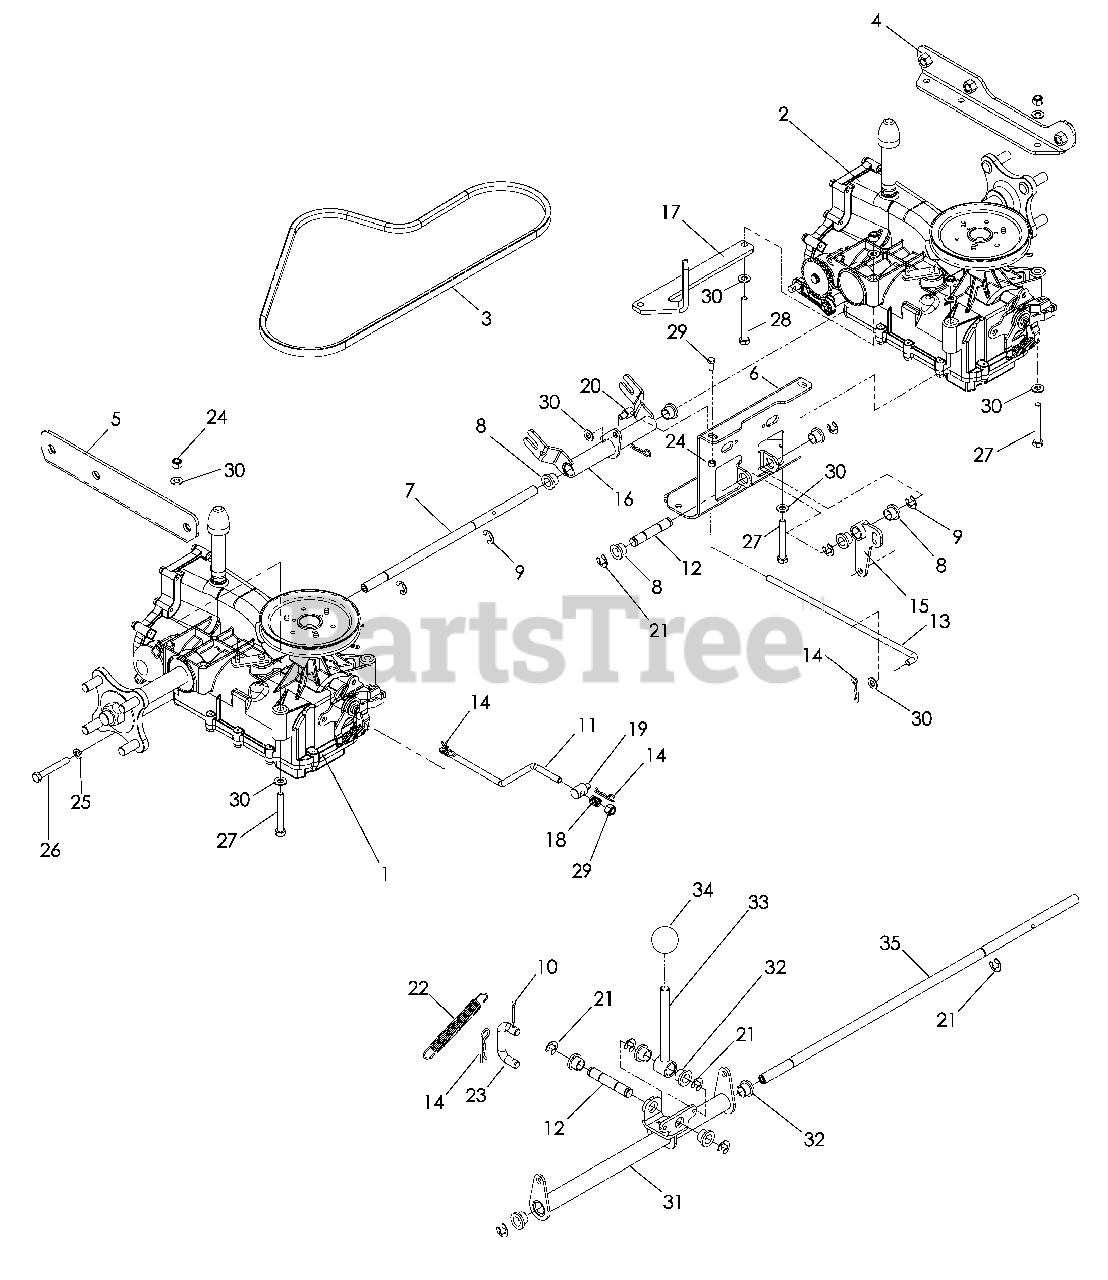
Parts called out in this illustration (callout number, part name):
1	IZT, LT AFTER S/N 042627905)
2	IZT, RT AFTER S/N 042627905
4	IZT SUPPORT, RIGHT
5	IZT SUPPORT, LEFT
6	IZT SUPPORT, REAR
7	IZT CONNECTOR
8	BUSHING, FLANGED
9	E-RING, ½"
10	PIN COTTER, 3/32 x ¾
11	IZT BYPASS LINKAGE
13	BRAKE LINKAGE
14	HAIRPIN COTTER
15	BRAKE BELLCRANK, RR
16	BRAKE BELLCRANK, FT
17	CLUTCH TIE DOWN
18	SPRING, TANK MOUNT
20	ADJ. SWIVEL, SHORT
21	E-RING, ½"
23	BRAKE LINKAGE
24	NUT 5/16-18 HEX NYLOC
25	LOCKWASHER, 5/16
26	HCS, 5/16-18 x 2¼, GR8
27	HCS, 5/16-18 x 2½
28	HCS, 5/16-18 x 2¾
29	HCS, 5/16-18 x ¾
30	WASHER, 5/16, SAE
31	ACTUATOR ARM
32	BUSHING, FLANGED
